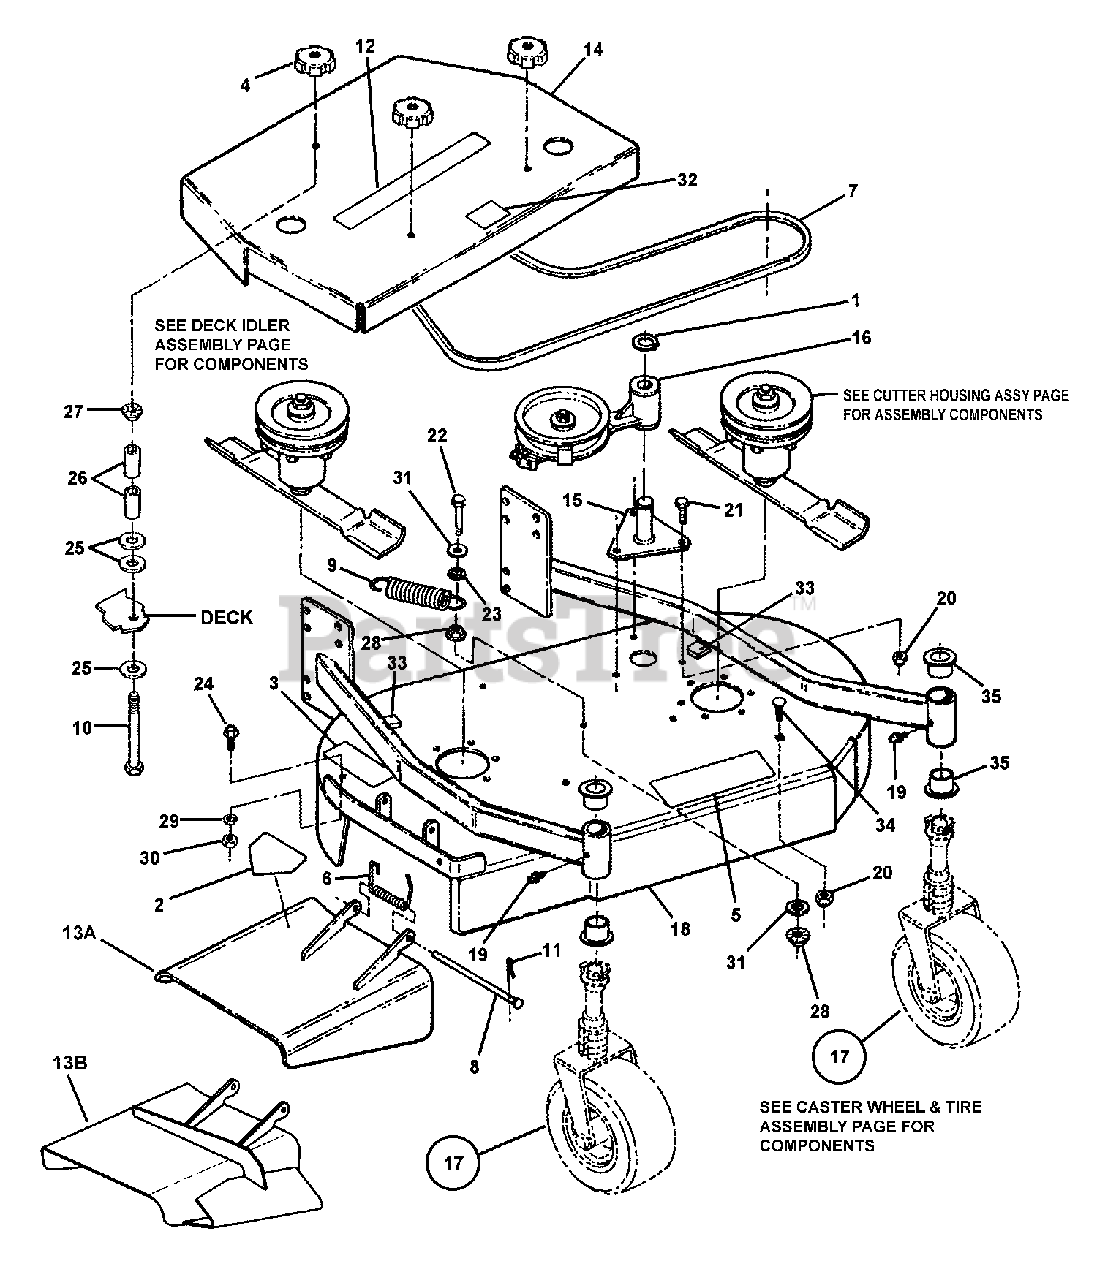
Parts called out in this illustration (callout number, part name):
1	RING, 1" External Retaining
2	DECAL, Warning (CPSC Cut Finger)
3	DECAL, Warning
3	DECAL, Danger, Guard, Catcher
4	KNOB, Hood (5/16-18 thread)
5	DECAL, Caution- Operator Instruction
6	SPRING, Chute
7	V-BELT, 36" Deck Drive Sect. HB
8	HINGE PIN, Chute
9	SPRING, Idler
10	SCREW, 5/16-18 x 4-1/2" Hex Head Cap, GR 5
11	COTTER PIN, 3/32 x 1"
12A	DECAL, SNAPPER Pro w/Trademark
12B	DECAL, SNAPPER Pro
13A	DEFLECTOR, 36" (Weldment)
13B	CHUTE, 36" Ansi Compliant (Weldment)
14	COVER, 36"
15	PIVOT, Idler Arm (Weldment)
16	ASSEMBLY, Idler Arm, 36"
17	ASSEMBLY, Caster (Red)
18	WELDMENT, 36" Deck, Fixed Height, Express
19	FITTING, 1/4-28 Straight Lube
20	NUT, 3/8-16 HEX NYLON LOCK
21	BOLT, 3/8-16 X 1" GD5 CZ
22	BOLT, 3/8-16 X 2, GD5, CZ
23	RETAINER, 3/8" Bolt
24	BOLT, 1/2-13 x 1-1/4" Hex Flange Lock, GR 5
25	WASHER, 3/8" I.D. Flat
26	SPACER
27	NUT, 5/16-18 Hex Flange Lock, GR 5
28	NUT, 3/8-16 Hex Flange Lock
29	WASHER, 1/2" Split Lock
30	NUT, 1/2-13 HEX
31	WASHER, 13/32" Flat
32	DECAL, 36" Deck
32	DECAL, 36" Silver
34	BOLT, 3/8-16 x 3/4" Short Neck Carriage, GR 5
35	BUSHING, Caster
